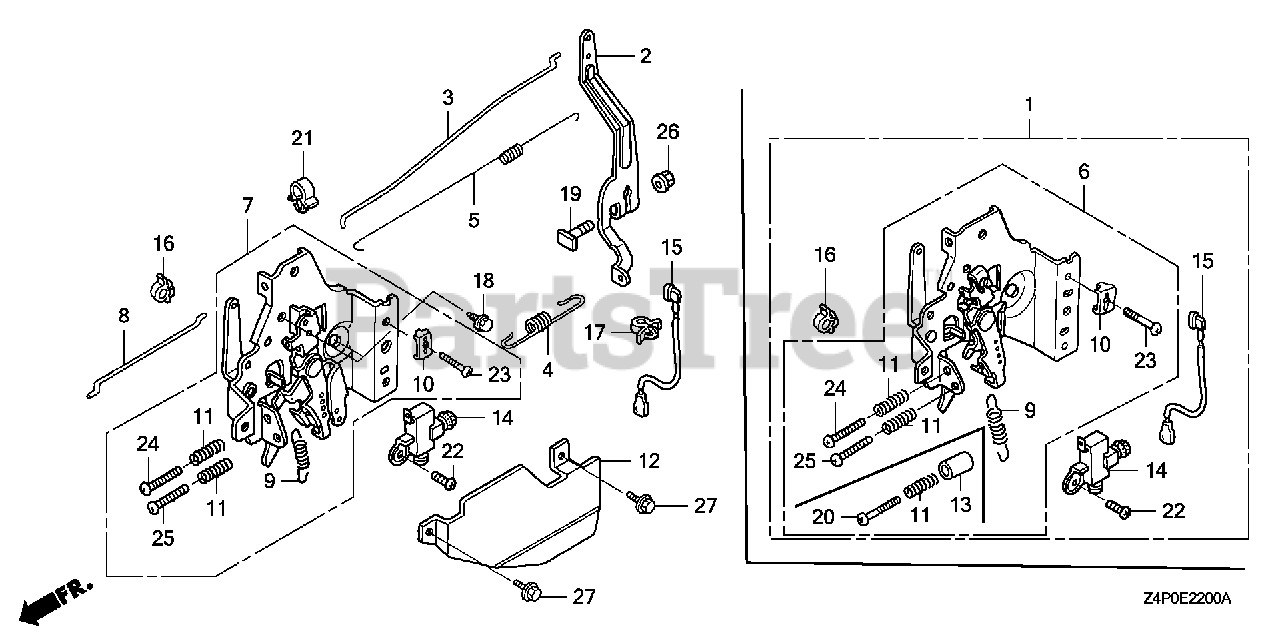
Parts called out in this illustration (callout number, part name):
2	ARM, GOVERNOR
3	ROD, GOVERNOR
4	SPRING, GOVERNOR
5	SPRING, THROTTLE RETURN
7	CONTROL ASSY.
8	ROD, CHOKE
9	SPRING, LEVER
10	HOLDER, CABLE
11	SPRING, CONTROL ADJUSTING
12	PROTECTOR, CONTROL
18	BOLT, FLANGE (6X12) (CT200)
19	BOLT, GOVERNOR ARM
21	CLIP, WIRE HARNESS
23	SCREW, PAN (5X16)
24	SCREW, PAN (5X20)
25	SCREW, PAN (5X28)
26	NUT, FLANGE (6MM)
27	BOLT, FLANGE (6X10)
